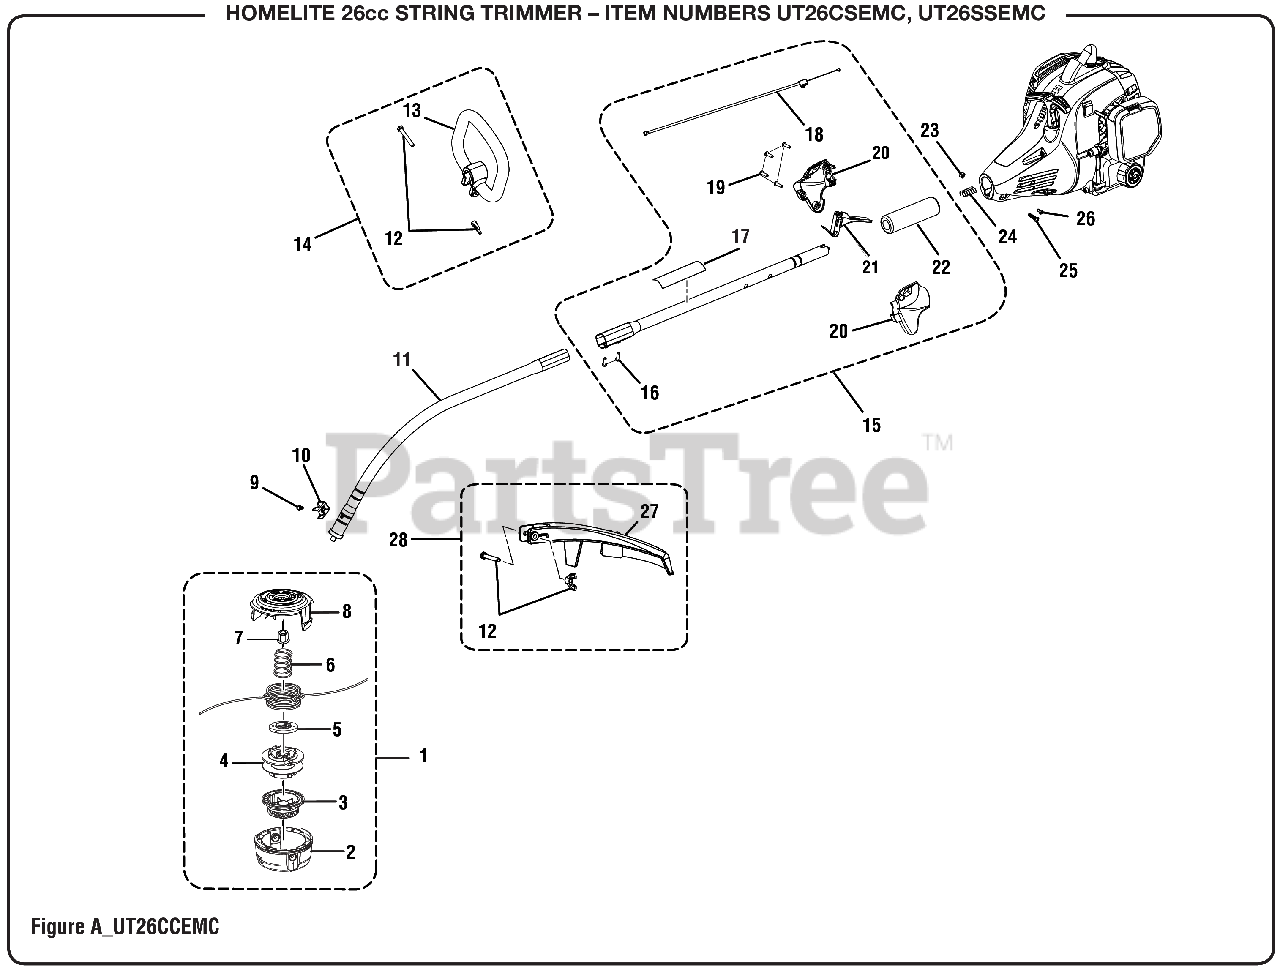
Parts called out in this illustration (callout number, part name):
1	Trimmer Head Assembly
2	Lower Housing
3	Bump Knob (Gray)
4	Spool Assembly
5	String Guide
6	Compression Spring
7	Flange Nut (M8)
8	Upper Housing
9	Screw (#10-32 x 3/8 in., Hex Washer Hd. S.T.)
11	Lower Boom Assembly
12	Fastener Parts Kit
13	Front Handle
14	Front Handle Assembly
15	Boom Assembly
16	Set Screw (M5 x 10 mm, Hex Soc. Hd.)
17	Icon Warning Label
18	Throttle Cable
19	Screw (M4 x 20 mm, T20 Torx Pan Hd. T.Fl.)
20	Trigger Handle Assembly
21	Throttle Trigger
22	Rubber Grip
23	Hex Nut (M6.3 x 1)
24	Compression Spring
25	Screw (M6 x 20 mm, T27 Torx Button Hd.)
26	Screw (M4 x 8 mm, T25 Torx Pan Hd. T.F.)
27	Grass Deflector
28	Grass Deflector Assembly
